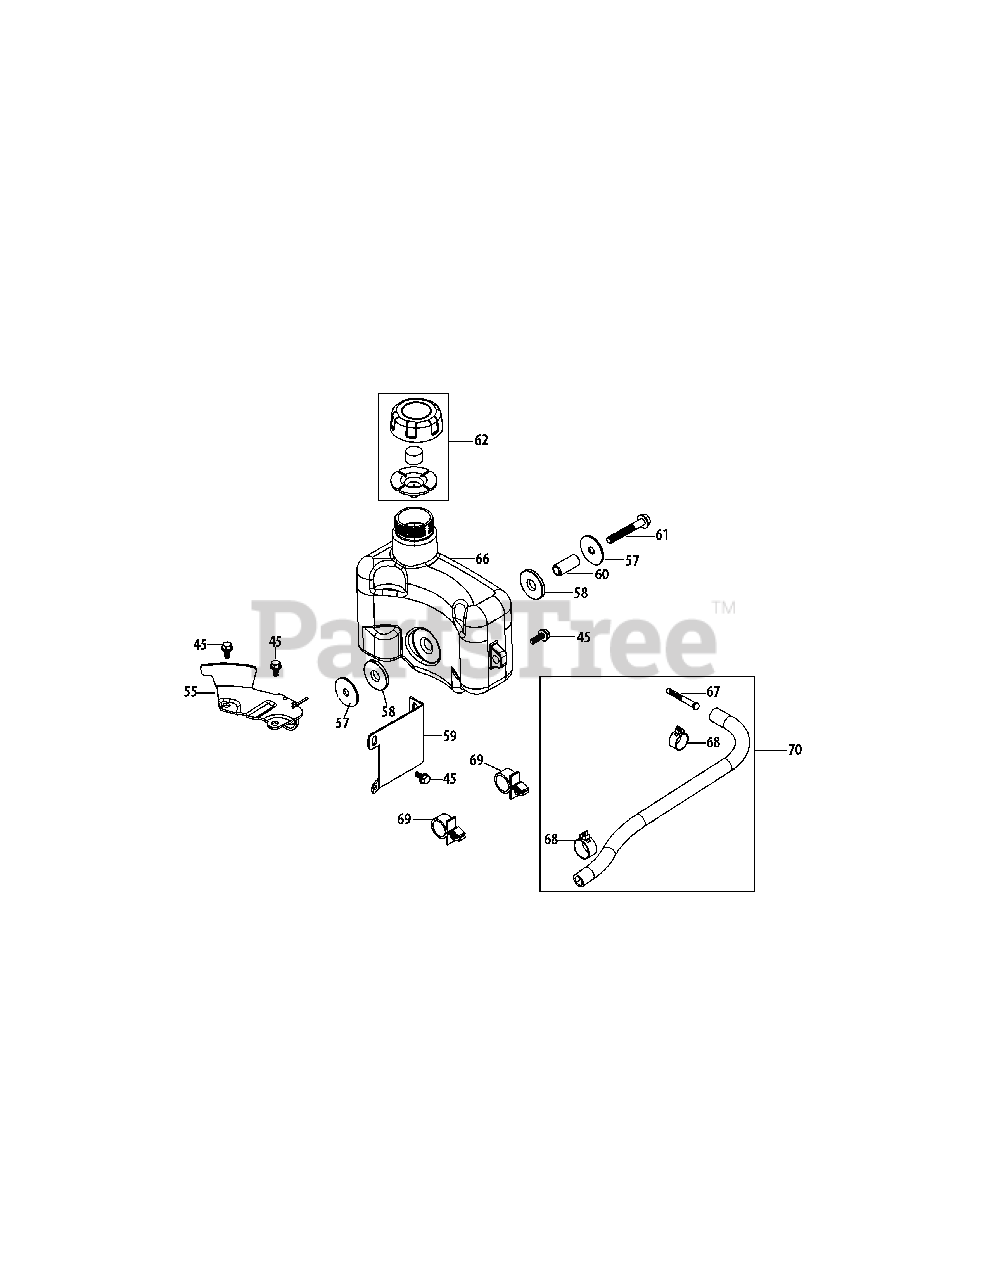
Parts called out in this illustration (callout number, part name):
45	Bolt M6×14
55	Fuel Tank Bottom Bracket
57	Fuel Tank Washer
58	Rubber Bushing
59	Fuel Tank / Label Bracket
60	Fuel Tank Bushing
61	Fuel Tank Bolt M8x50
62	Fuel Cap Assembly
66	Fuel Tank Assembly
67	Fuel Filter
68	Fuel Hose Clamp
69	Plastic Support Clamp
70	Fuel Line Kit
